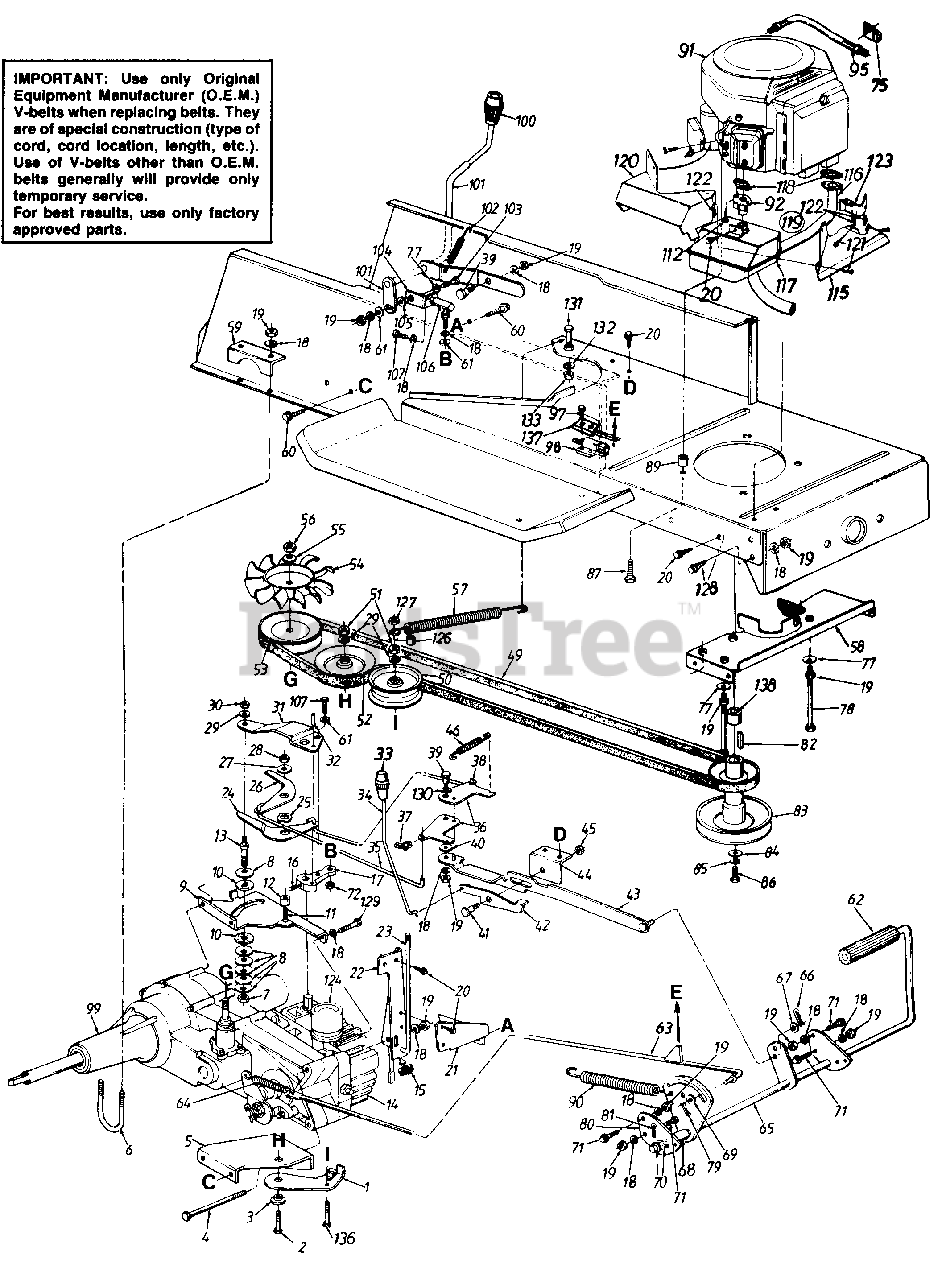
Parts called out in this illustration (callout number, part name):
1	Idler Bracket
2	Hex Bolt 3/8-16 x 2.0" Lg.
3	Shld. Spacer .625" I.D.
4	Hex Bolt 5/16-18 x 4.5" Lg. (Gr. 5)
5	Idler Plate
6	U-Bolt 5/16-18 x 1.75" Lg.
7	Hex L-Nut 3/8-24 Thd.
8	Bell-Wash. .40" I.D. x 1.13"
9	Mounting Bracket
10	Friction Washer
11	Rib Neck Bolt 5/16-24 x .84" Lg.
14	Hydrostatic Pump
15	Rubber Washer .33" I.D.
17	Pintle Shift Lever
18	L-Wash. 5/16" I.D.
19	Hex Nut 5/16-18 Thd.
20	Hex TT-Tap Scr. 1/4-20 x .5"
21	Reinforcement Plate
22	Transmission Torque Brkt.
23	Release Valve Rod
24	Reverse Arm
25	Spring Washer .625" I.D.
26	Forward Arm
27	Fl-Wash. .344" I.D. x 1.0"
28	Hex Cent. L-Nut 5/16-24 Thd.
29	L-Wash. 3/8" I.D.
30	Hex Nut 3/8-24 Thd.
31	Pintle Arm Ext. Plate
32	Roll Pin 1/4" Dia. x .75" Lg.
33	Knob
35	Connection Rod
36	Balancer Bracket
37	Rod End Clevis Clips-R.H.
38	Rod End Clevis Clips-L.H.
39	Shld. Bolt .437" Dia. x .268"
40	Fl-Wash. .344" I.D. x 1.12"
41	Shld. Bolt .437" Dia. x .35"
42	Lock-Up Bracket
43	Neutral Return Brkt. Ass'y.
45	Hex Cent. L-Nut 5/16-18 Thd.
46	Ext. Spring 2 5n Lg.
49	"V"-Belt
51	Hex Nut 3/8-16 Thd.
52	Idler Pulley 4.0" O.D.
53	Transmission Pulley
55	Bell-Wash. .56" I.D. x 1.125"
56	Hex Jam Nut 9/16-18 Thd.
57	Extension Spring
58	Belt Guard Brkt. Ass'y.
59	Bracket
60	Hex B-Tap Scr. 5/16-18 x .5"
61	Flat Tooth Washer 5/16" I.D.
62	Foot Pad
63	Brake Rod Ass'y.
64	Ext. Spring 3.67" Lg.
65	Clutch Brake Pedal Ass'y.
66	Intern. Cotter Pin 5/16" Dia.
67	Fl-Wash. .385" I.D. x .62n
68	Spacer.63" I.D.
69	Fl-Wash. .385" I.D. x .62n
70	Fl-Wash. .635" I.D. x 1.0"
71	Hex TT-Tap Scr. 5/16-18 x 7/8"
72	Hex Nut 5/16-24 Thd.
77	Bell-Wash. .345" I.D. x .88"
78	Hex Bolt 5/16-18 x 4.0" Lg.
79	Cotter 3/32" Dia. x .75" Lg.
80	Pedal Brkt.
81	Cotter Pin 8/32n Dia. x 1.0" Lg.
82	Sq.-Key 1/4" x 2.0"
83	Engine Pulley
84	Fl-Wash. 7/16" I.D. x 1.25"
85	L-Wash. 7/16n l.D. (H.D.)
86	Hex Bolt 7/16-20 x 1.5" Lg.
87	Hex TT-Tap Scr. 3/8-16 Thd.
89	Spacer 5/16" I.D.
90	Extension Spring 6.11n Lg.
91	Engine
92	Inlet Tube Ass'y.
95	Hydraulic Hose 13n Lg.
97	Truss Mach. B-Tap Scr. #10 x .5" Lg.
98	Safety Switch
101	Speed Selector Lever Ass'y.
102	Ext. Spring 2 75n Lg.
103	Hex Bolt 5/16-18 x 1.25" Lg.
104	Connection Brkt.
105	Shoulder Nut
106	Ball Joint 5/16-24 Thd.
107	Hex Bolt 5/16-24 x .75" Lg.
112	Bolt w/Washer
115	Muffler Heat Shield-Front
116	Formed Tube Ass'y.
117	Exhaust Muffler Sub Ass'y.
118	Gasket
119	Muffler Ass'y. Comp.
120	Muffler Heat Shield
121	Hex Wash. Tap Scr. #10 x 5n Lg.
122	Speed Nut #10-24 Thd.
123	Front Heat Shield Ext.
124	Reservoir
126	Spacer .375" I.D. x .503
127	Hex Jam Nut 3/8-16 Thd.
128	Hex Wash. TT-Tap Scr. 5/16-18 x 62" Lg.
129	Hex Bolt 5/16-18 x 4.75" Lg.
130	Spr.-Wash. .445" I.D. x .75" O.D.
131	Hex Bolt 1/4-20 x 1.25" Lg.
132	L-Wash. 1/4" I.D.
133	Hex Nut 1/4-20 Thd.
136	Hex Bolt 3/8-16 x 2.5" Lg.
137	Switch Plate
138	Engine Pulley Spacer
